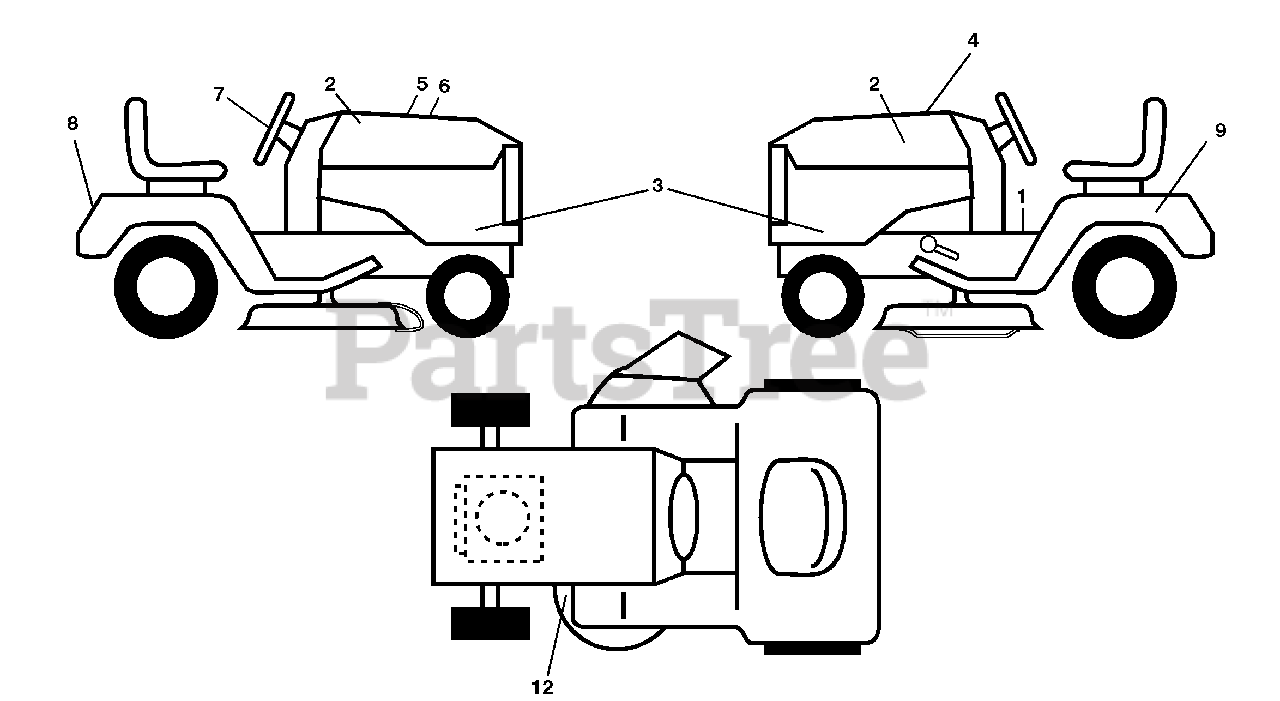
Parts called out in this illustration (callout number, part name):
1	Decal, Operators
2	Decal, Hood
3	Decal, Hood Panel SD
4	Decal, Hood Top Insert
5	Decal, Customer Respons.
6	Decal, Replacement
7	Decal, Steering Wheel
8	Decal, Fender
9	Decal, Battery Dnge/Poi
12	Decal, Mower V-Belt Schematic
